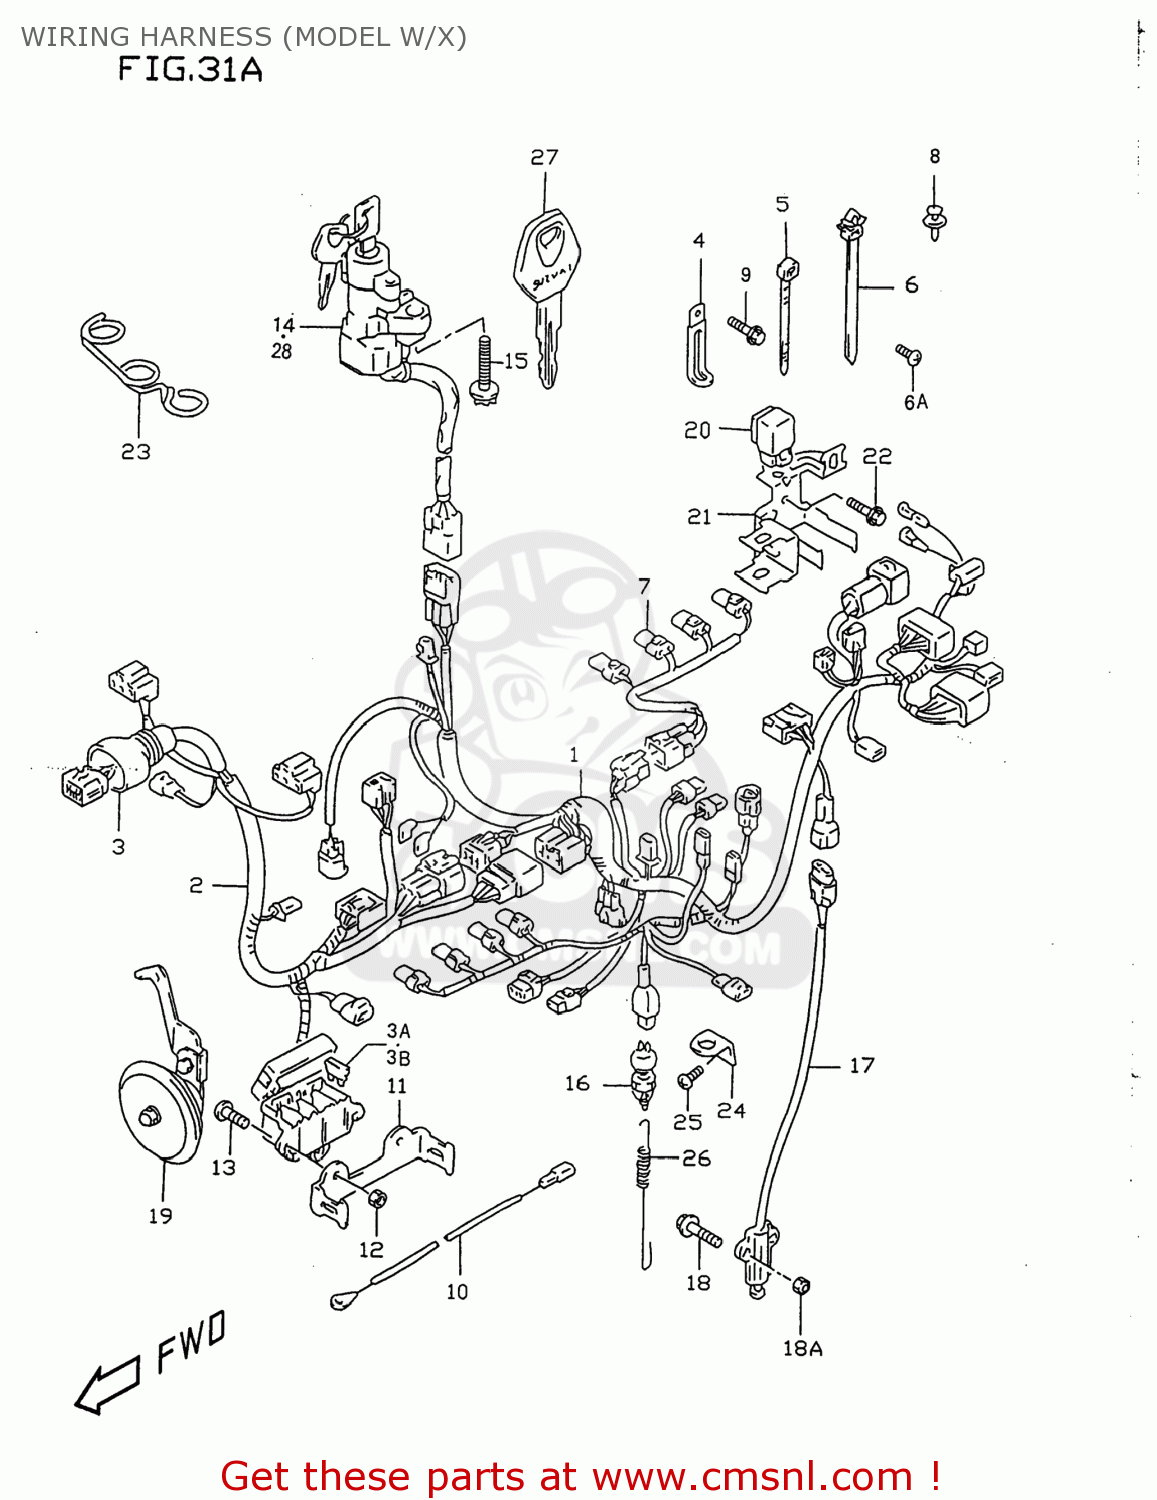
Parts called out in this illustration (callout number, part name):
1	HARNESS,WIRING NO.1
2	HARNESS,WIRING NO.2
3	COVER,SPEEDOMETER COUPLER
3A	FUSE(10A)
3B	FUSE(15A)
4	CLAMP(L:45)
5	CLAMP(L:125)
6	CLAMP
6A	SCREW 6X12
7	WIRE,INJECTOR LEAD
8	CLIP(BLACK)
9	BOLT
10	WIRE,OIL PRESSURE SWITCH LEAD
11	BRACKET,FUSE BOX
12	NUT,COWLING SCREEN
13	SCREW 5X12
14	LOCK ASSY,STEERING
15	BOLT(8X20)
16	SWITCH ASSY,STOP LAMP
17	SWITCH ASSY,SIDE STAND WARNING
18	BOLT
18A	NUT
19	HORN ASSY
20	RELAY ASSY
21	BRACKET COMP,FUEL PUMP RLY
22	BOLT
23	GUIDE,WIRING HARNESS
24	BRACKET,STOP LAMP SWITCH
25	SCREW
26	SPRING
27	KEY,BLANK
